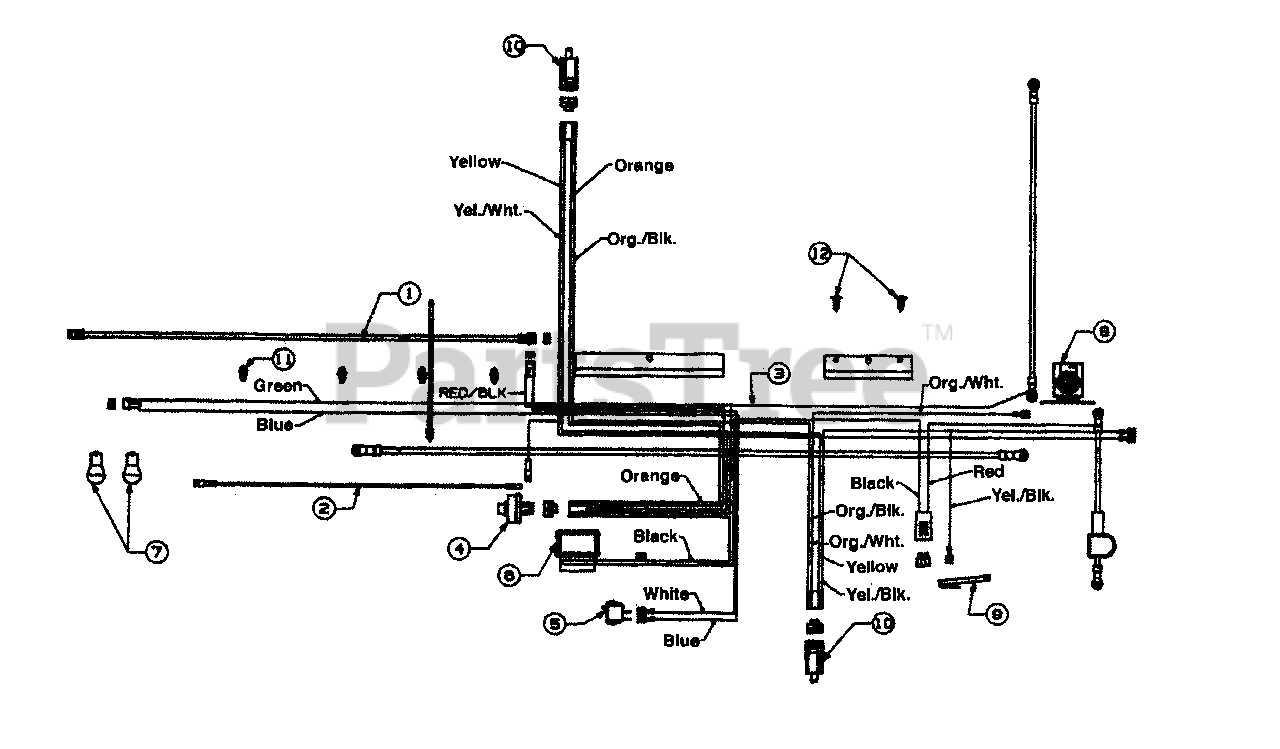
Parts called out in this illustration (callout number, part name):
1	Harness Adapter (Alt.)
2	Harness Adapter
3	Wire Harness w/Light Switch & Amp
4	Ignition Switch W/O Light Switch & Amp
5	Light Switch
6	Ammeter
7	Bulb
8	Solenoid
9	Safety Switch (Reverse)
10	Safety Switch
11	Wire Retainer Clip
12	Ratchet
